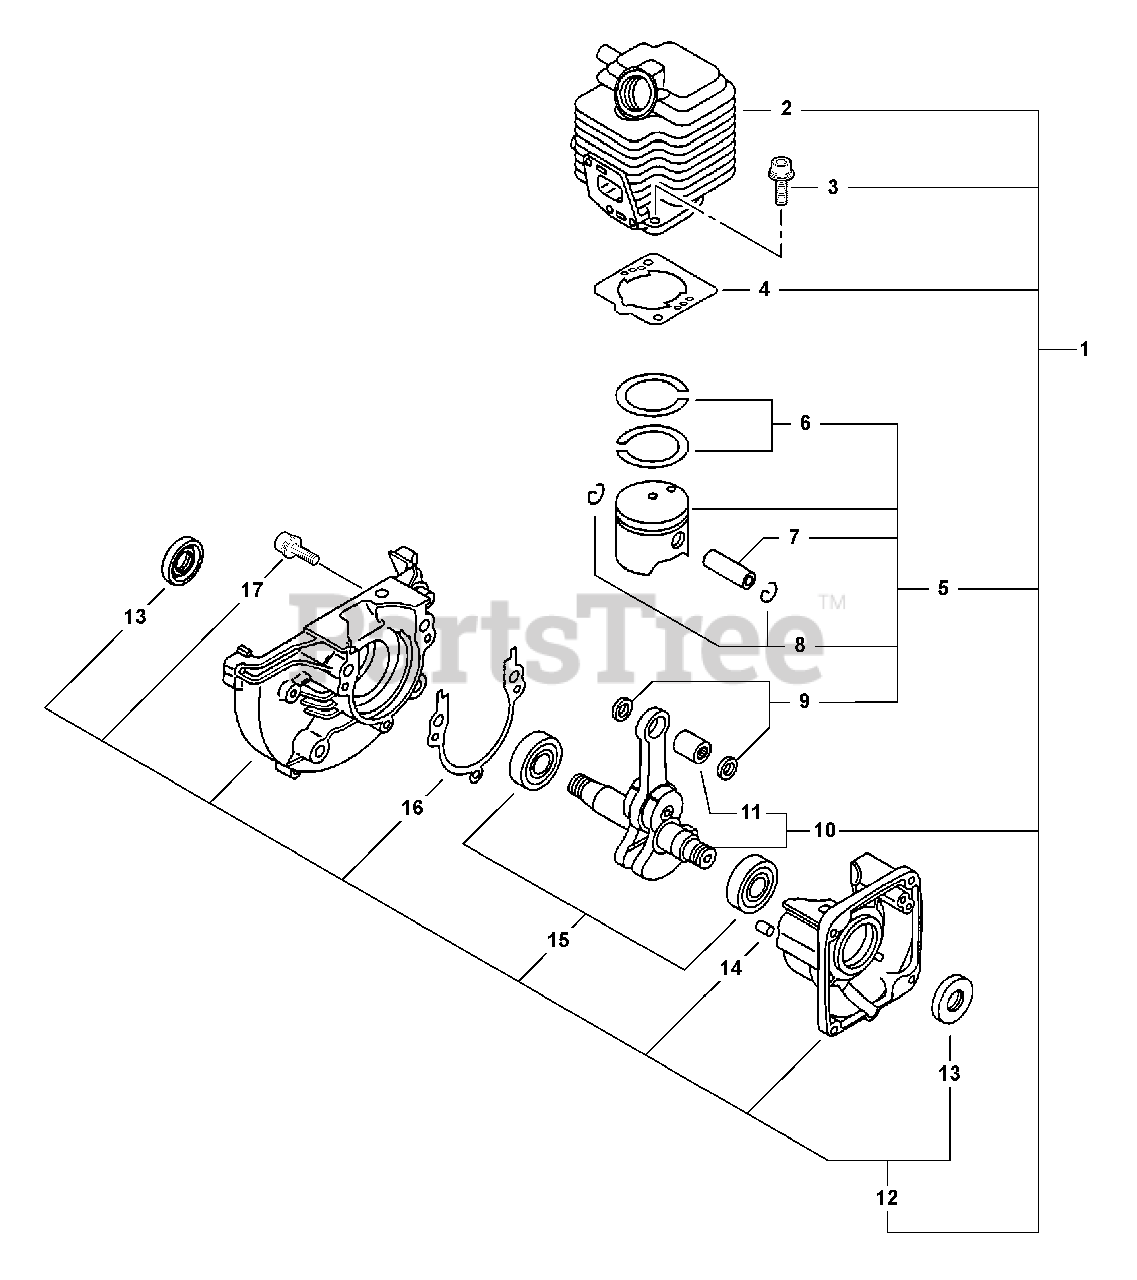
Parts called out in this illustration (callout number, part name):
1	Short Block
2	Cylinder
3	Screw 5x22
4	Gasket, Cylinder
5	Piston Kit
6	Ring, Piston
7	Pin, Piston
8	Circlip, Piston Pin
9	Spacer, Piston Pin
10	Crankshaft Asy
11	Bearing, Needle
12	Crankcase Kit
13	Oil Seal
14	Dowel Pin
15	Bearing, Ball - 6201
16	Gasket, Crankcase
17	Screw 5x28
